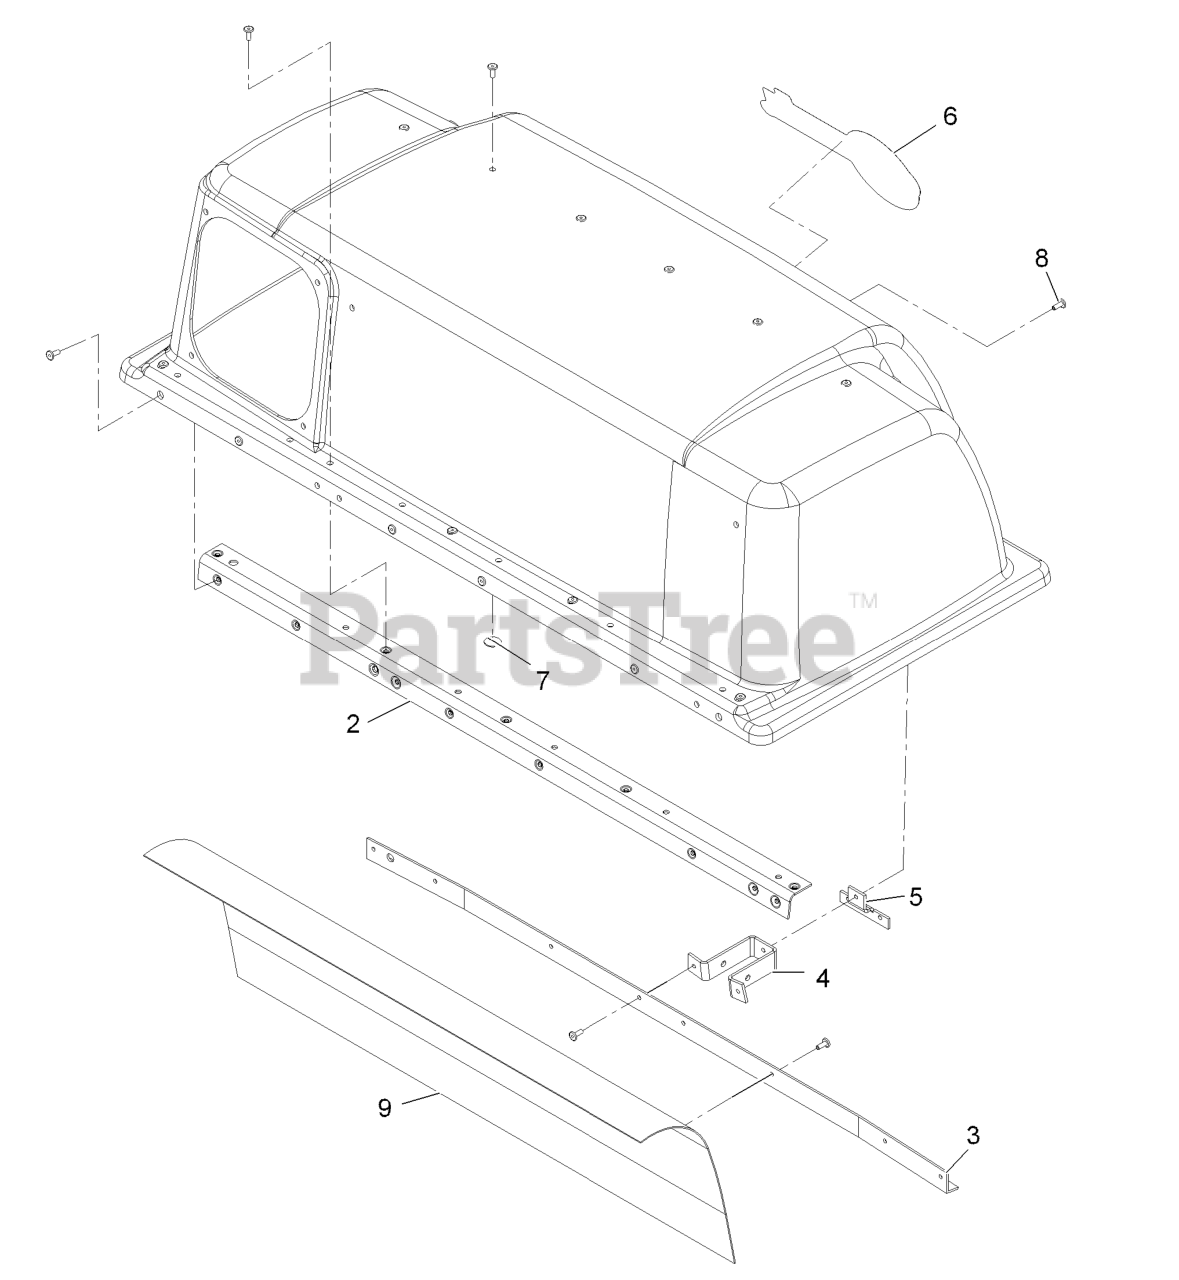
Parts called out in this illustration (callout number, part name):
2	STIFFENER-BAGGER, TOP
3	SUPPORT-SCREEN
4	ANCHOR-LATCH
5	REINFORCEMENT-LATCH
6	DECAL, EXMARK LOGO
7	WASHER-FLAT
8	RIVET-BLIND
9	SCREEN-BAGGER
